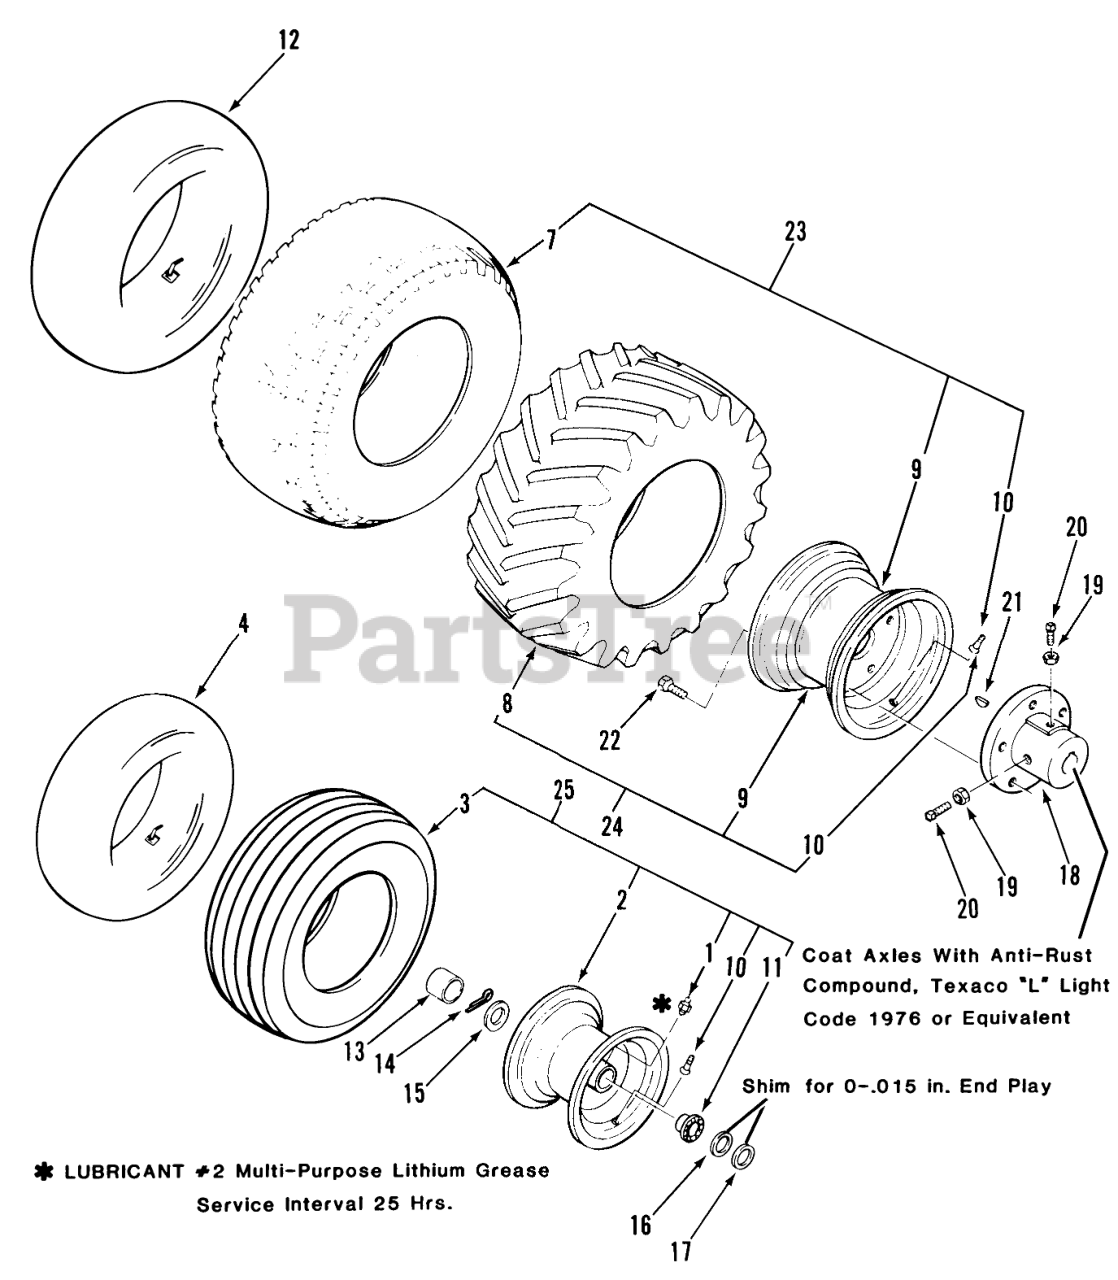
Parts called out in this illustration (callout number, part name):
1	Zerk
2	Front Wheel (includes Item 1, 10, 11)
3	Front Tire 16 x 6.50-8
4	TUBE-INNER
7	Tire
7	TIRE 9.50 X 12
7	Rear Tire 23 x 10.50-12 GT-1800 Only
8	Tire-Cleat, Rear
9	Rear Wheel GT-1100, GT-1600 Only
9	WHEEL RIM
10	VALVE
11	Ball Bearing
12	TUBE-INNER
12	Rear Tube
13	HUB CAP-FLAT BLACK
14	COTTER PIN-4
15	WASHER-WHEEL
16	WASHER
17	WASHER-SHIM
18	Hub-Rear
18	Hub Rear
19	Nut
20	Screw-Set
21	WOODRUFF KEY
21	KEY-WOODRUFF
22	Lug Nut
23	Rear Wheel and Tire Assy Turf GT-1142 Only
23	Rear Wheel and Tire Assy Turf GT-1642 Only
23	Rear Wheel and Tire Assy Turf GT-1848 Only
24	Right Rear Wheel and Tire Assy-Cleat
24	Left Rear Wheel and Tire Assy-Cleat
25	Front Wheel and Tire Assy
